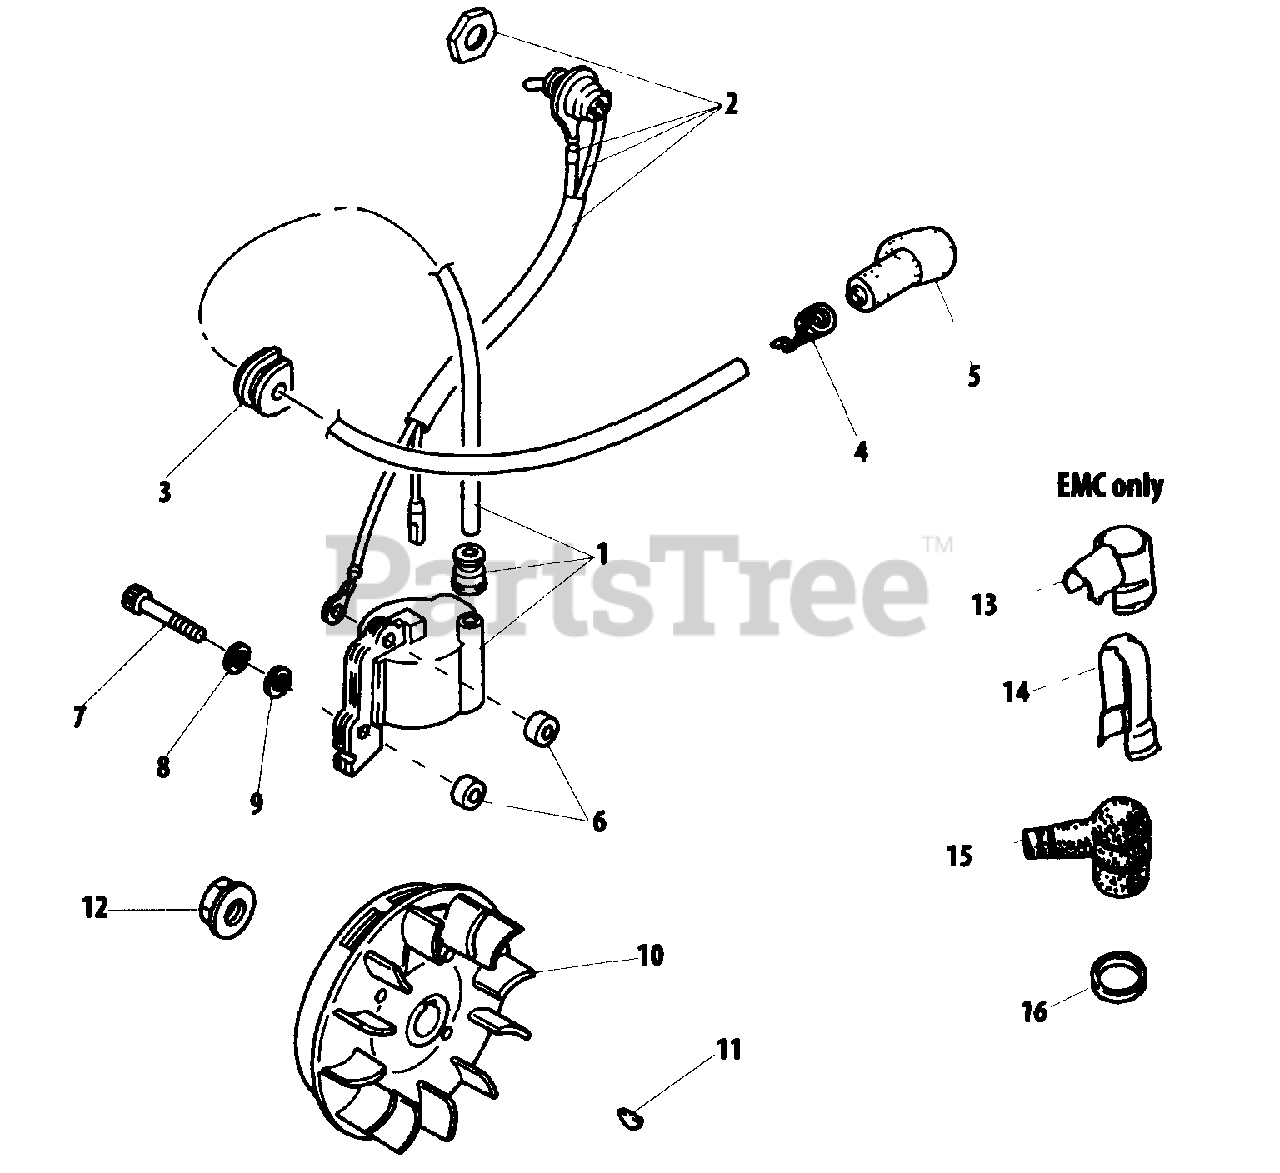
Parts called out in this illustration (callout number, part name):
1	IGNITION COIL ASSY
2	SWITCH
3	GROMMET
4	TERMINAL, SPARK PLUG CAP
5	CAP, SPARK PLUG
6	INSULATOR
7	SCREW - 4X26
8	LOCKWASHER - 4
9	WASHER
10	FLYWHEEL
11	KEY - 3X10
12	NUT - 8
13	CAP, SPARK PLUG
14	SHIELD
15	CAP, SPARK PLUG
16	SEAL, DUST
